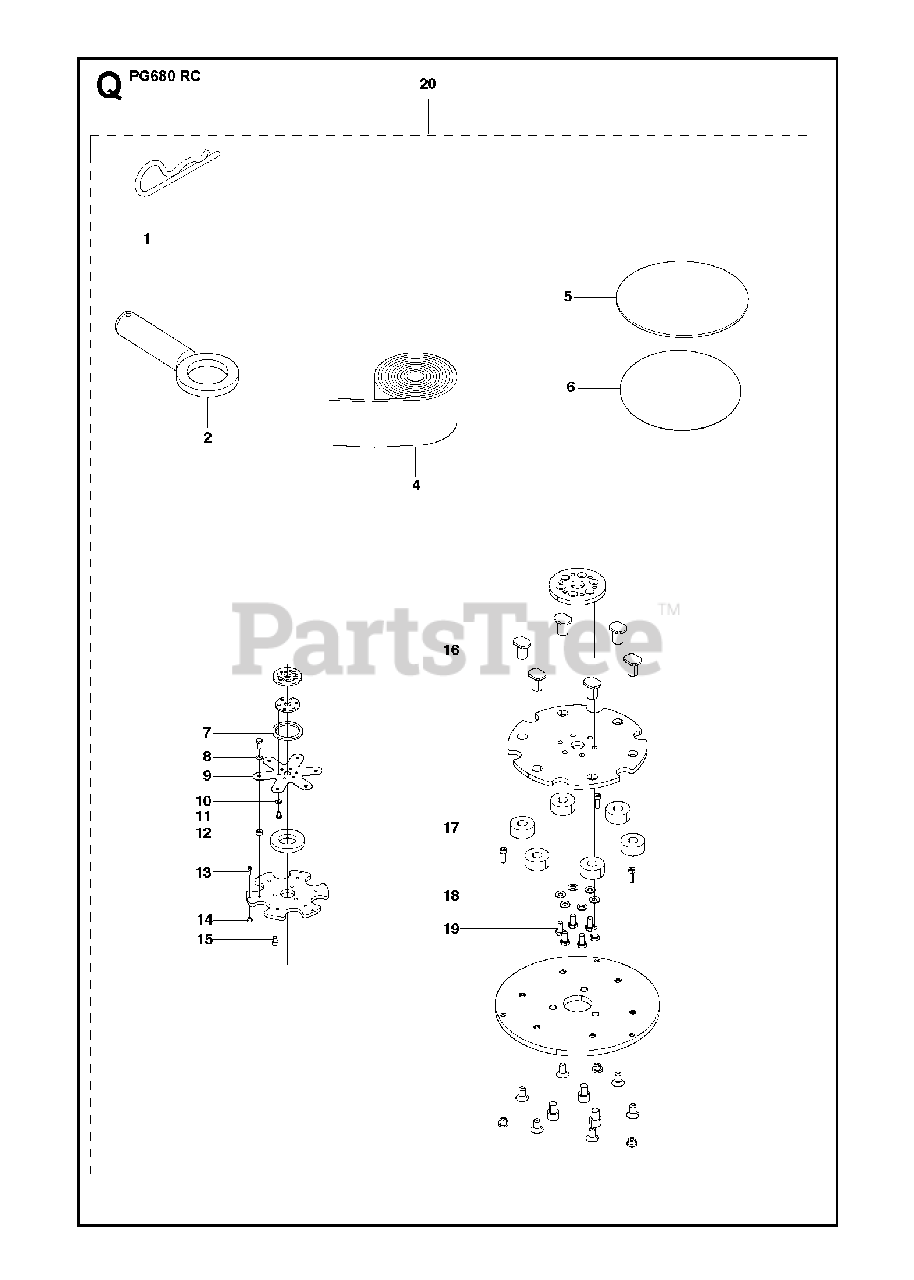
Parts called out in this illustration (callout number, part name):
1	SPRING COTTER
8	WASHER
10	WASHER
11	SCREW EHHM
18	WASHER
19	SCREW EHHM
